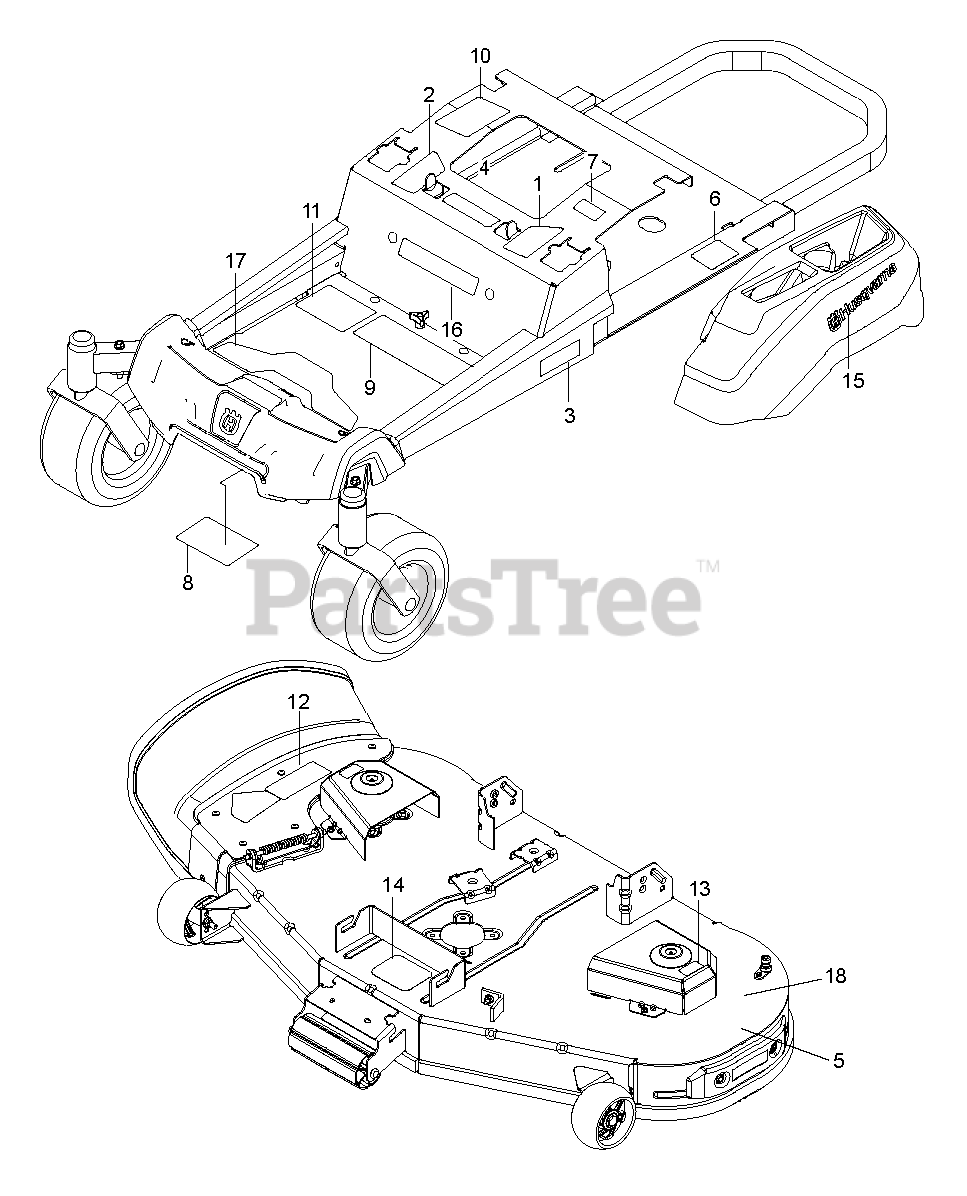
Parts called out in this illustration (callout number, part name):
1	DECAL.ZTR.RZ.THRTL/PRKBRK.V2.L
2	DECAL.ZTR.RZ.THRTL/PRKBRK.V2.R
3	DECAL ZTR SIDE RAIL GRAPHIC DE
4	EURO DECAL-BATTERY WARNIN6
5	DECAL.54DECK.CLEARCUT.VER2.18
6	DECAL, DO NOT TOW
7	DECAL, EXITING MOWER
8	DECAL, SERVICE
9	DECAL ZTR WARNING DECAL DECAL.
10	DECAL.WARNING.CUST.RESP.E85.
11	DECAL ZTR BRAND GRAPHIC DECAL.
12	DECAL.TRACT/ZTR.DECKWARN.HUSQ
13	DECAL.DECK.CLEARCUT.NOSTEP
14	DECAL BELT ROUTING DECAL DECAL
15	DECAL.HUSQVARNA.210MM
16	DECAL ZTR BRAND GRAPHIC DECAL.
17	PAD.RZ.FOOTREST.PLATE
18	DECAL DECK DECAL DECAL.DECK.WA
